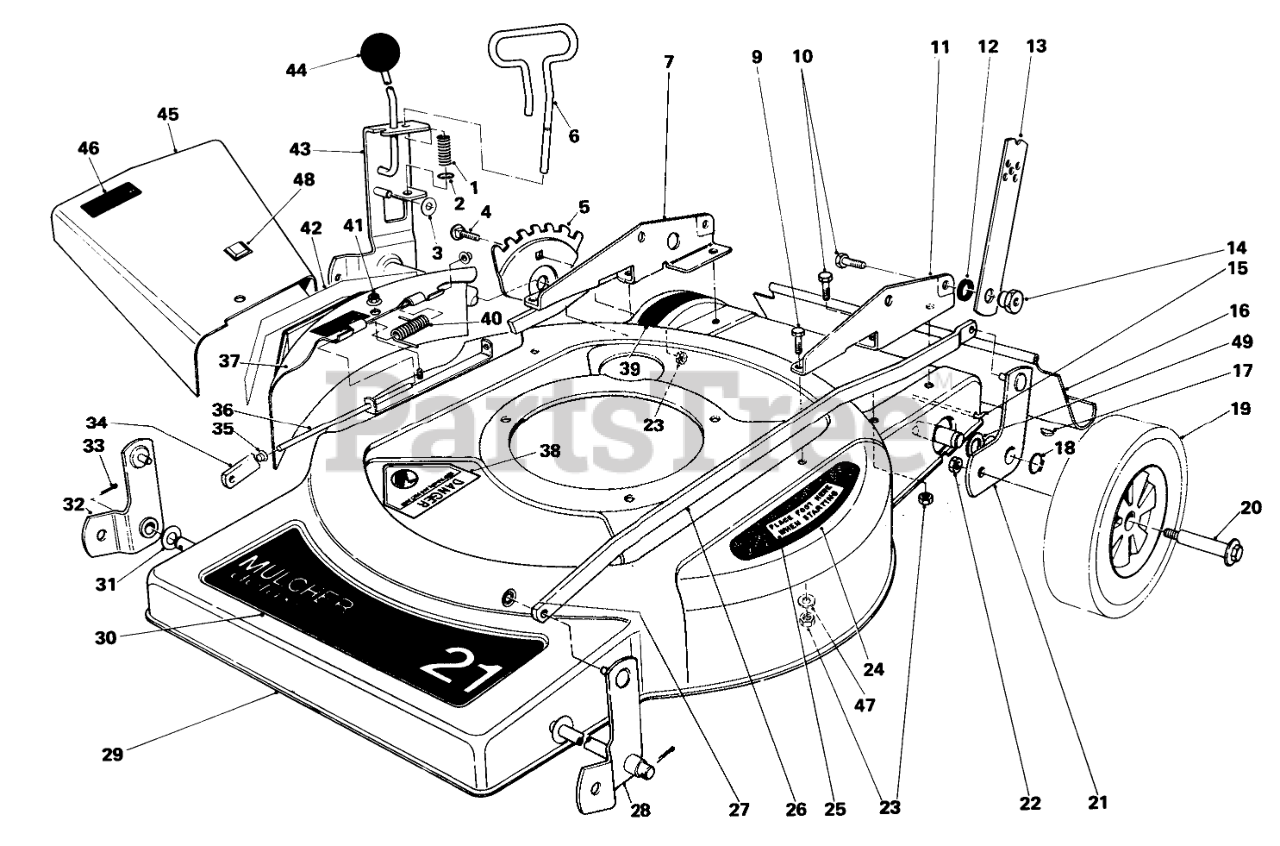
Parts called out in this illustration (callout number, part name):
1	SPRING-COMPRESSION
2	E-RING
3	WASHER-FLAT
4	Carriage Bolt
5	HOC ADJUSTMENT PLT
6	STOP ROD
7	Bracket Handle R.H.
9	SCREW-HH
10	SCREW-HH
11	Bracket-Handle R.H.
12	SPACER
13	HANDLE LATCH
14	HANDLE PIVOT NUT
15	SHIELD ROD
16	SHIELD - TRAILING
17	KEY-WOODRUFF
18	RING-RETAINING
19	WHEEL & TIRE ASM
20	BOLT-WHEEL
21	Pivot Arm
22	Nut
23	NUT-LOCK, CONE
24	PAD STEP
25	Decal Step Pad
26	Spanner Link L.H.
27	NUT-PUSH
28	LH FRT PIVOT ARM WA
29	Housing
30	Decal-Deck
31	WASHER
32	Pivot Arm
33	PIN-COTTER
34	Spanner Link R.H.
35	PUSHNUT-CAP, WASHER
36	DEFLECTOR PIVOT ROD
37	Mulcher Cover
38	DECAL-DANGER
39	Decal Height of Cut
40	Spring
42	Decal-Cover
43	Pivot Arm Bracket
45	Deflector-Grass
46	Decal-Danger
47	WASHER-FLAT
48	Bumper
49	WASHER-FLAT
